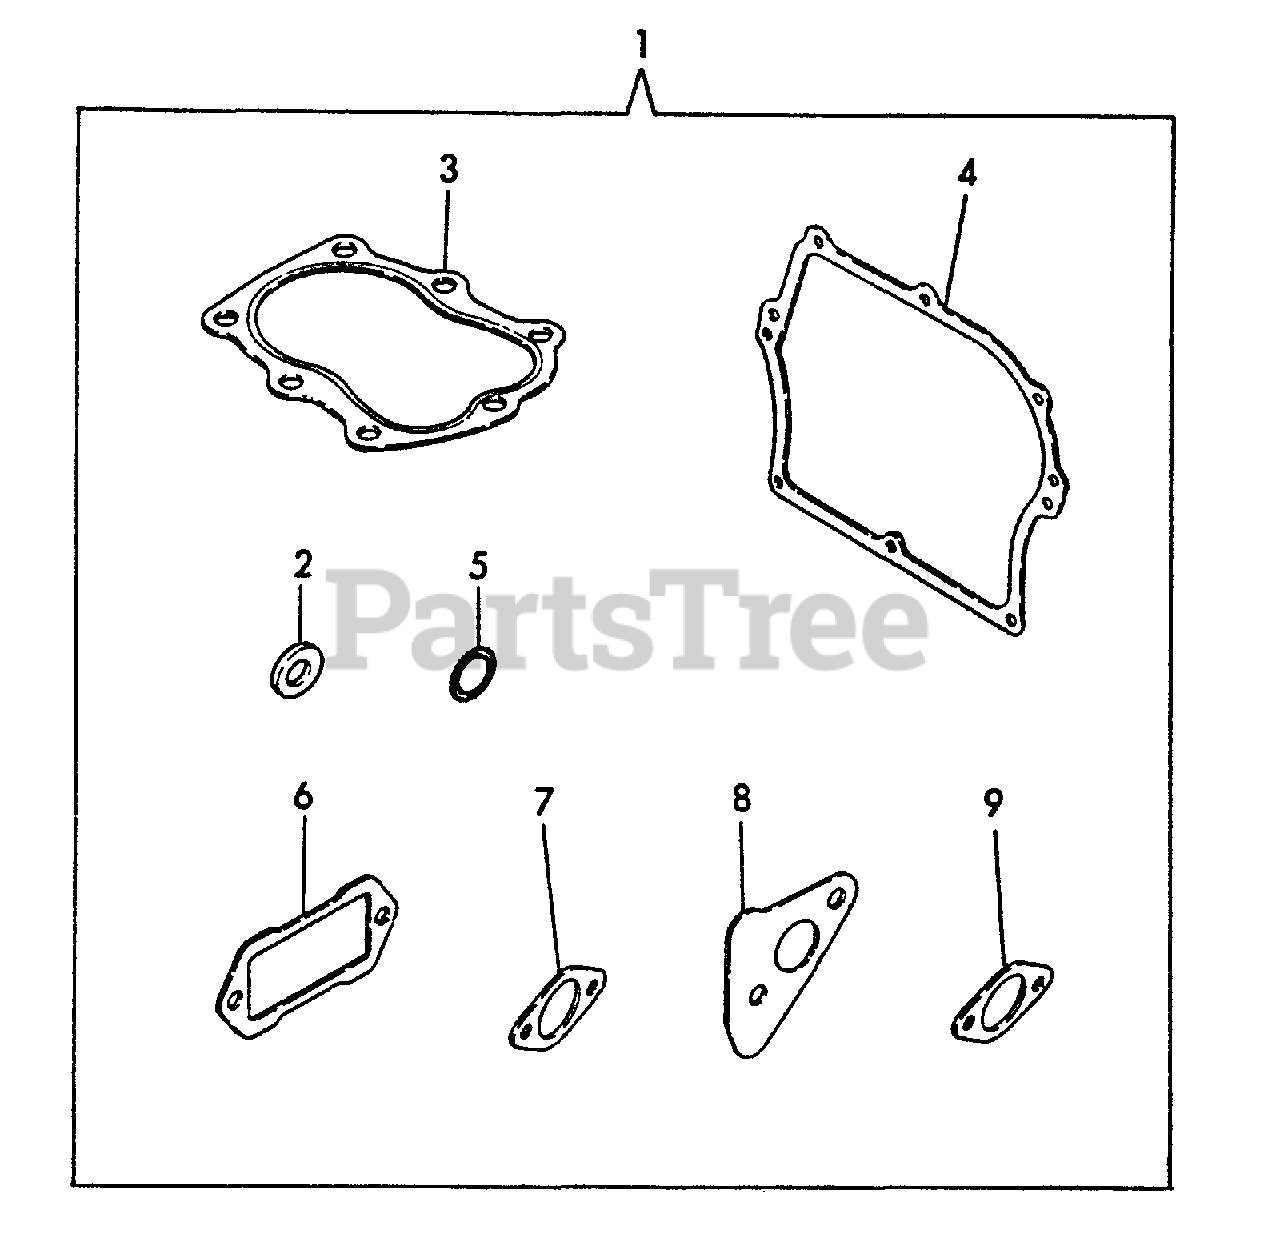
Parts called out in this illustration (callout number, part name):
1	GASKET KIT
2	GASKET
3	GASKET, CYLINDER
4	GASKET, SIDE COVER
5	O-RING - 18
6	GASKET, BREATHER
7	GASKET, INTAKE
8	GASKET, EXHAUST
9	GASKET, EXHAUST
